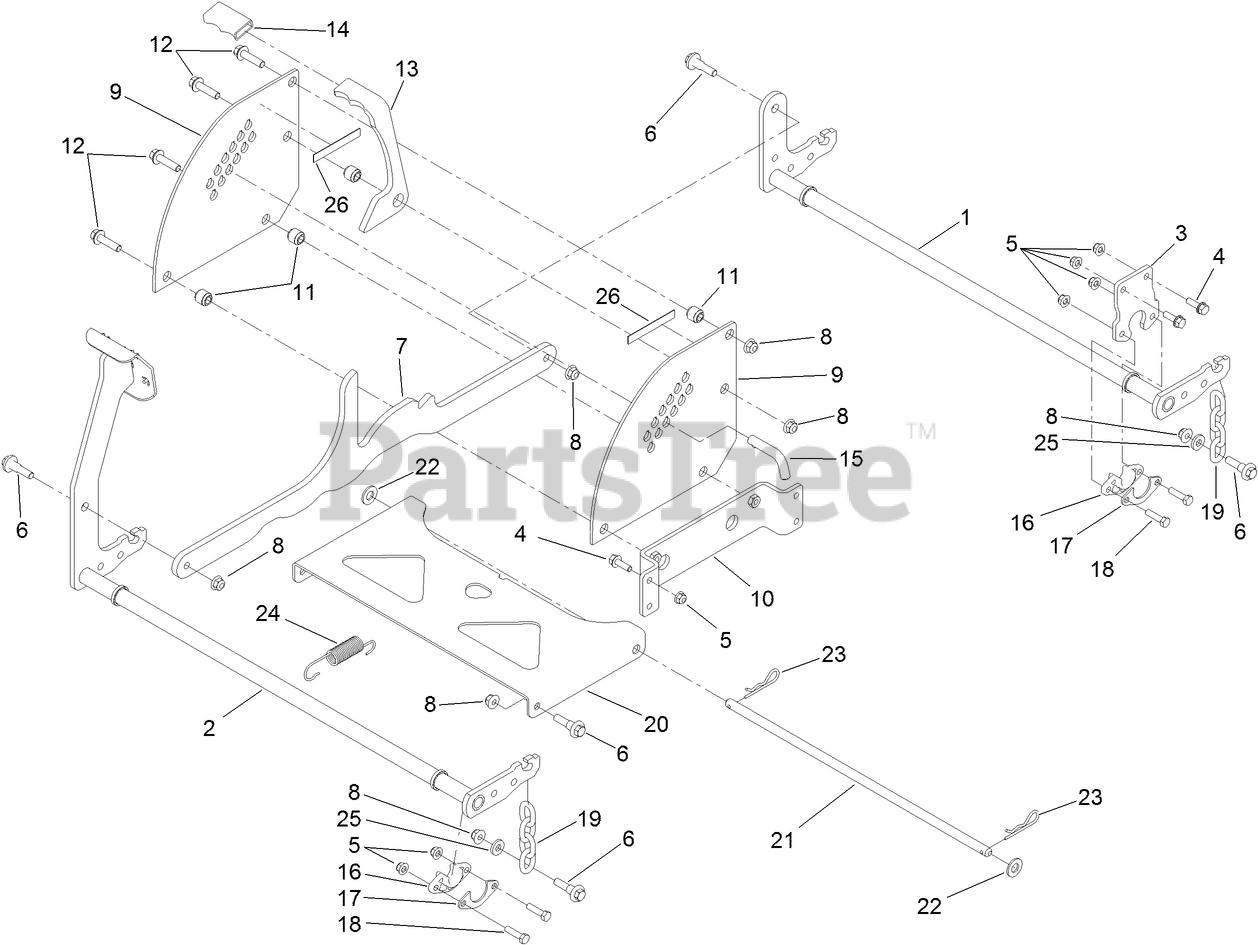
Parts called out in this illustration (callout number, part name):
1	PIVOT-REAR
2	PIVOT-FRONT
4	SCREW-HHF
5	NUT-HF, NI
6	BOLT-SHOULDER
7	LINK-HOC
8	NUT-HF, NI
9	PLATE-DECK, LIFT
10	PLATE-LIFT
11	SPACER-STEP, DOUBLE
12	SCREW-HHF
13	LOCK-TRANSPORT, HOC
14	GRIP-FLAT
15	PIN-HOC
16	BUSHING-FLANGE
17	GUSSET-LIFT, DECK
18	SCREW-HH
19	CHAIN-DECKLIFT
20	PAN-PIVOT, DECK
21	ROD-PIVOT, DECK
22	WASHER-FLAT
23	PIN-COTTER
24	SPRING-EXTENSION
25	SPACER
26	PAD-RUBBER
